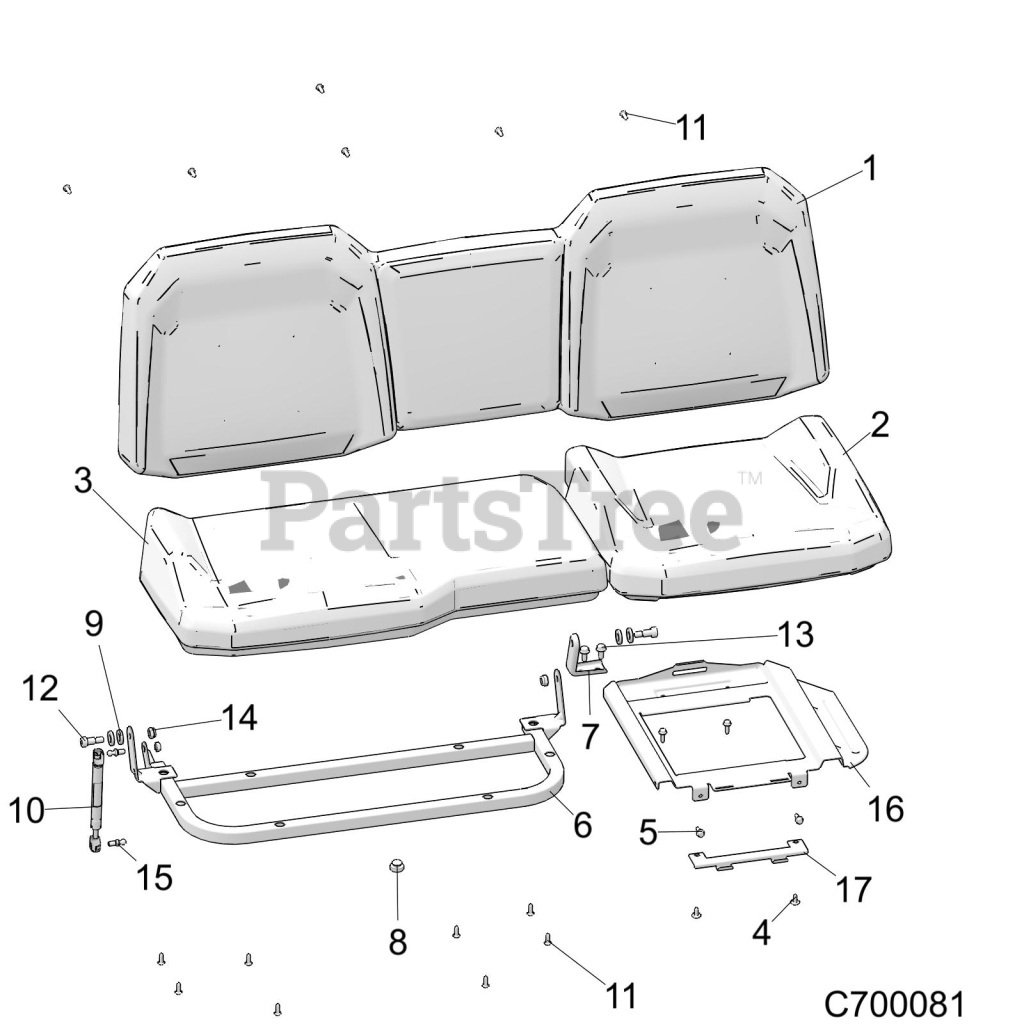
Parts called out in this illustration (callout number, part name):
1	ASM-SEAT,3PASS,BACK,GUNMETAL
2	ASM-SEAT,BTM,40,VINYL,GUNMETAL
3	ASM-SEAT,BTM,60,VINYL,GUNMETAL
4	SCR-M6X1X16 TR/TX-M
5	SCR-M6X1.0X20,HXHD,FLG,TDFM,BL
6	WELD-SEAT BASE,PASS,M.BLK
7	BRKT-SEAT PIVOT,BLK
8	BUMPER-RUBBER
9	WASHER-SEATBELT,RUBBER
10	SHOCK-GAS,285MM
11	SCR-TX TRUSS-#14X3/4,HI/LO ZBK
12	SCR-SHS-M10X1.5-M12X16 RIE
13	SCR-HWH-M8X1.25X20 TAP/R ZPB
14	NUT-HEX M10X1.5 8 ZOD NYL
15	BALL-END
16	BRKT-SEAT SUPPORT,FIXED,BLK
17	BRKT-SEAT PIVOT,FIXED,BLK
